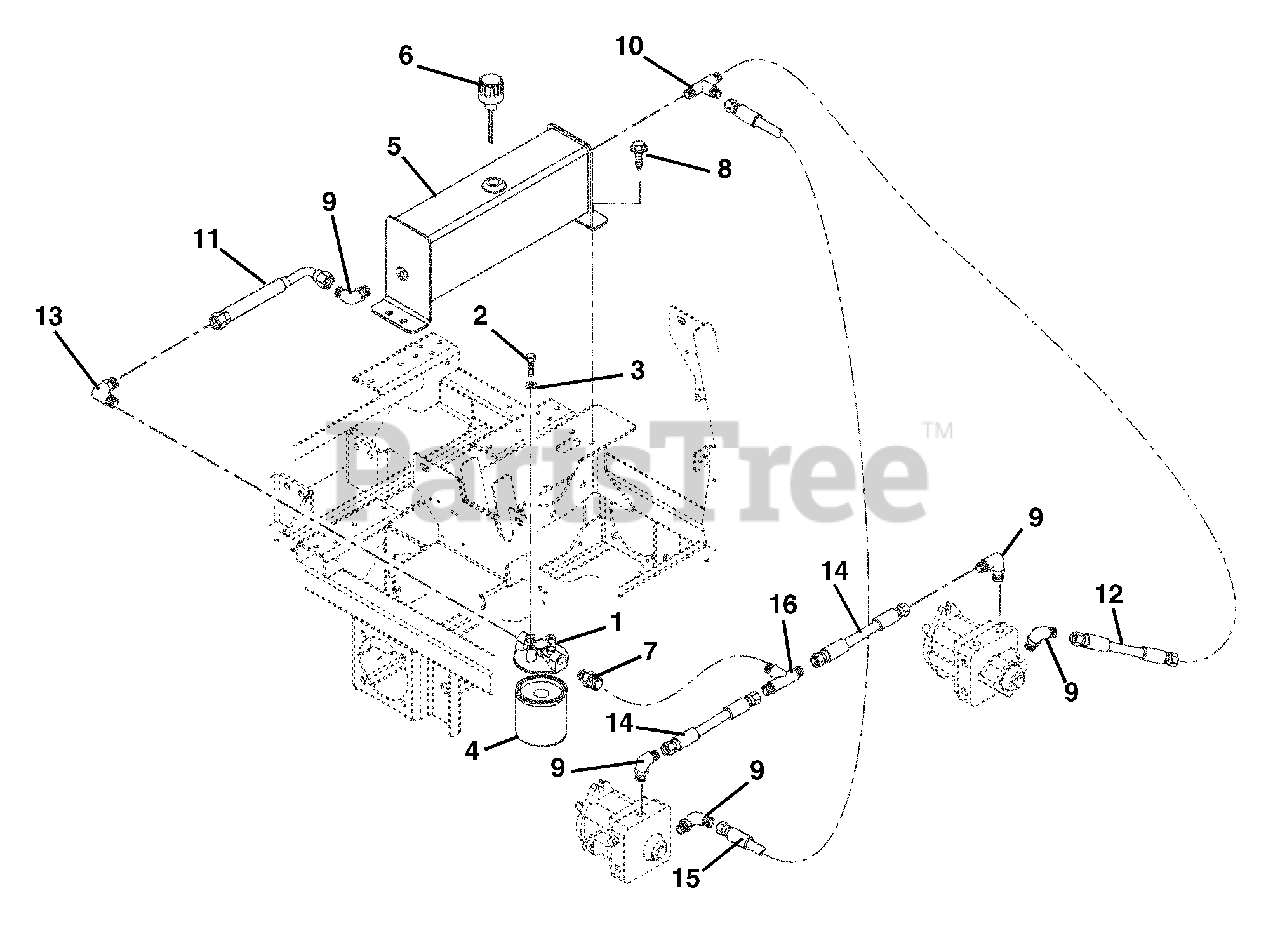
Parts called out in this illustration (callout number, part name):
1	Filter Housing
2	Bolt-Hex .25-20 x .50 Grade 5
3	Washer-Locking .25 x .062
4	Filter Element
5	Weldment, Hydraulic Tank
6	Breather, Dipstick
7	Adapter-Hydraulic Steel
8	Screw-Tapping .38-16 x .75 Hex Washer Head
9	Adapter-Hydraulic Elbow
10	Fitting, Hydraulic Tee
11	Hose-Hydraulic Valve to Tank
12	Hose, Hydraulic
13	Adapter, Elbow 90 Degree
14	Hose, Hydraulic .50
15	Hose, Hydraulic .50
16	Fitting Hydraulic Tee
